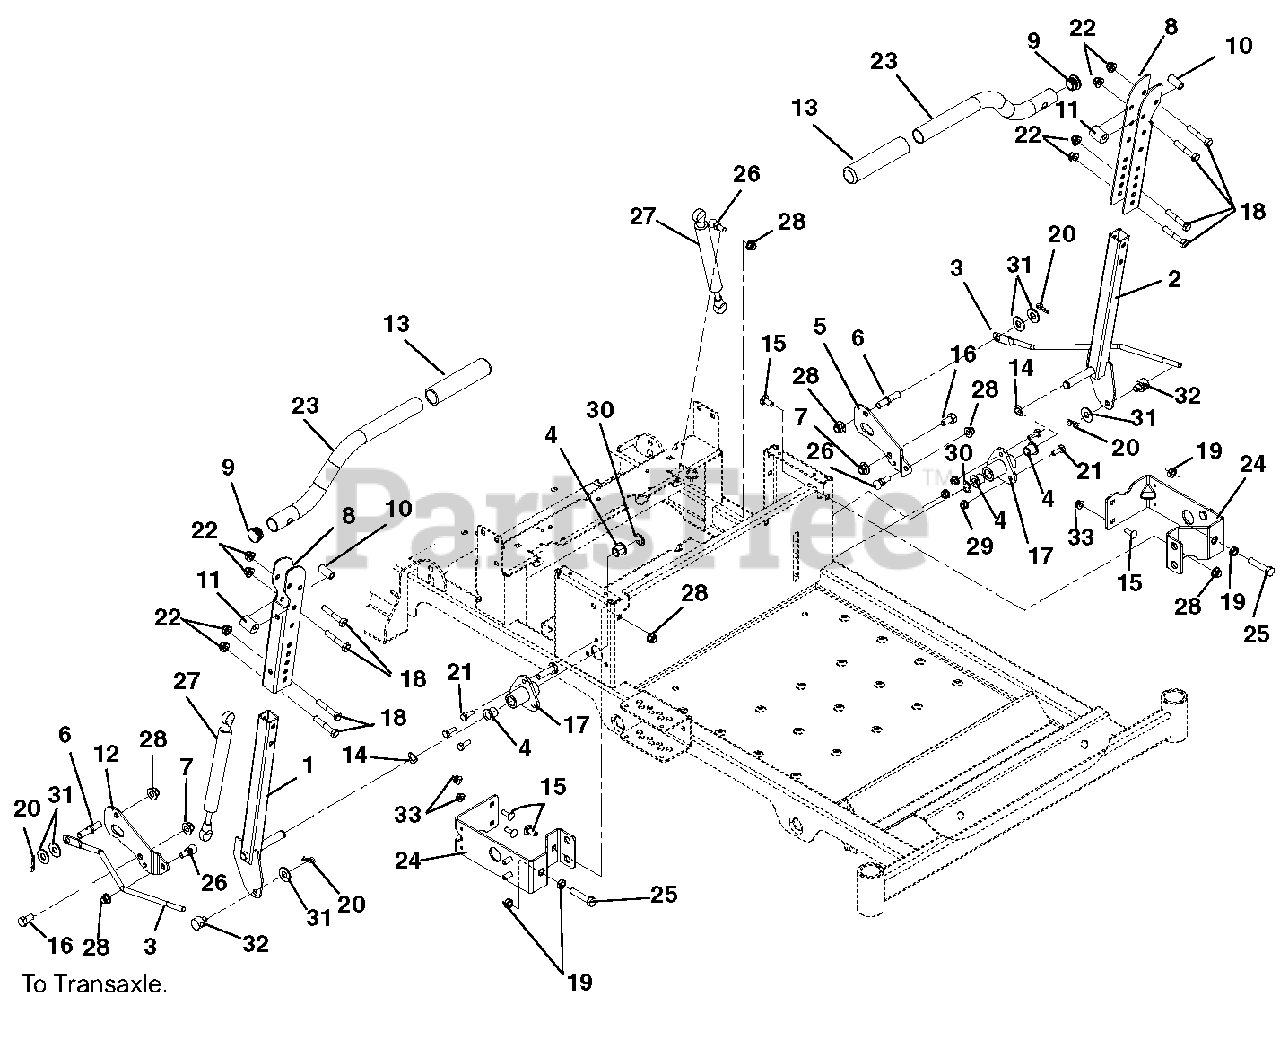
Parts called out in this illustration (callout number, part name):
1	Weldment, RH Control Arm
2	Weldment, LH Control Arm
3	Link, Steering
4	Bushing, Flanged .500 x .625
5	Plate, Damper LH
6	Pin, Trans
7	Nut, .38-16 Nyloc Flange
8	Channel, Upper Handlebar
9	Caplug, Handlebar
11	Eccentric
12	Plate, Damper RH
13	Grip, Handlebar
14	Washer, Flat-Steel .505 x .880 x .072
15	Bolt, Round Head Square Neck .31-18 x .75
16	Bolt, Hex .38-16 x .75 Grade 5
17	Bushing, Flanged
18	Bolt, Hex .31-18 x 1.75 Grade 5
19	Nut, Hex Jam .375-16
20	Pin, Hair Internal .08 x .18 x 1.18
21	Bolt, Hex .25-20 x .75 Grade 5 or
22	Nut, .31-18 Nyloc Flange
23	Handle, Steering
24	Bracket, Speed Adjustment/Seat Pivot
25	Bolt, Hex .375-16 x 1.750 Full Thread
26	Stud, Ball
28	Nut, Flange .31-18
29	Nut, Locking-Top-Flange .25-20 (not used with 07400034, item 21
30	Ring, Retaining External .500 x .042
31	Washer, Flat Steel .438 x 1.00 x .083
32	Trunnion, Brake .31-18
33	Nut, .25-20 Nyloc Flange
